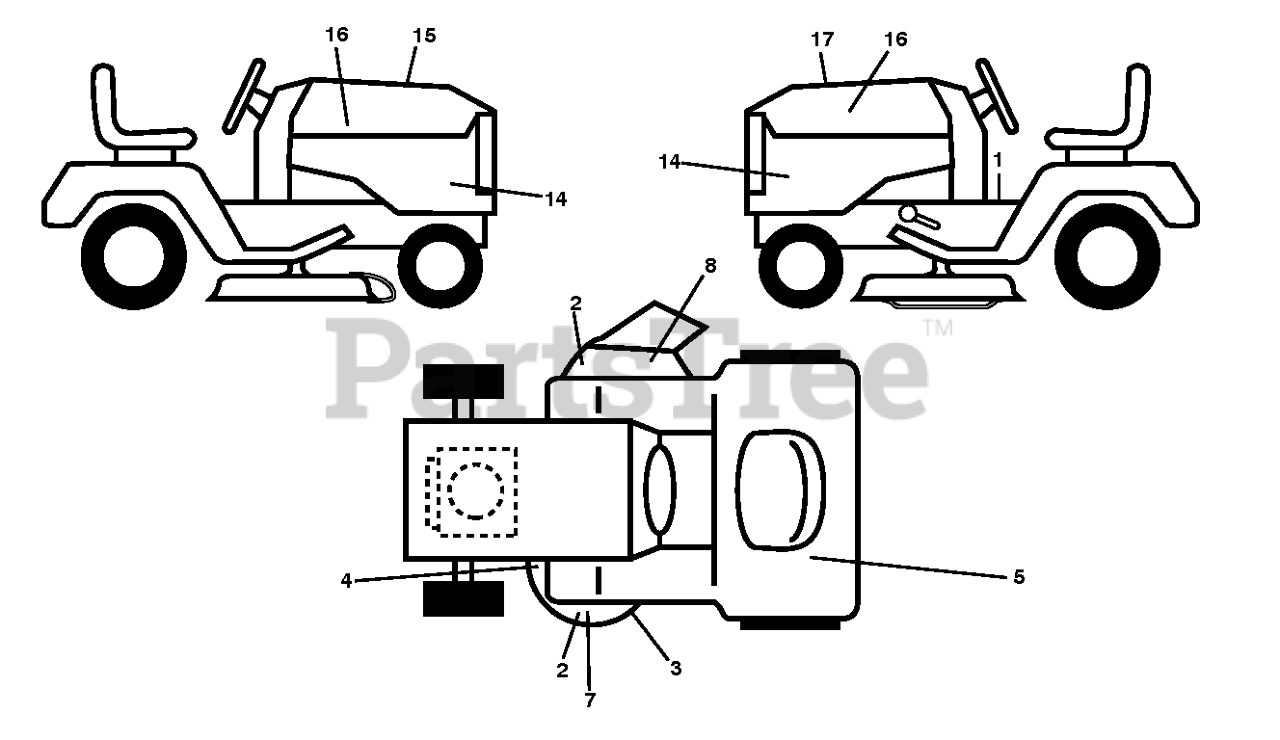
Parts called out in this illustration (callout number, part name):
1	DECAL.FENDER.WARNING.ENGLISH
2	DECAL.DECK.CLEARCUT.NOSTEP
3	DECAL.MOWER.SCH.48/54.PREM
4	DECAL DECK DECAL DECAL.DECK.WA
5	DECAL.RESERVEFUELSELCTR.ENG
7	DECAL DECK DECAL DECAL.48DECK.
8	DECAL.TRACT/ZTR.DECKWARN.HUSQ
14	DECAL TRACTOR SIDE PANEL DECAL
15	DECAL.WARNING.CUST.RESP.E85.
16	DECAL.BADGE.170MM.TEXTLOGO.
17	DECAL.RPL.KW.FR.TGB.48F.K66AL
